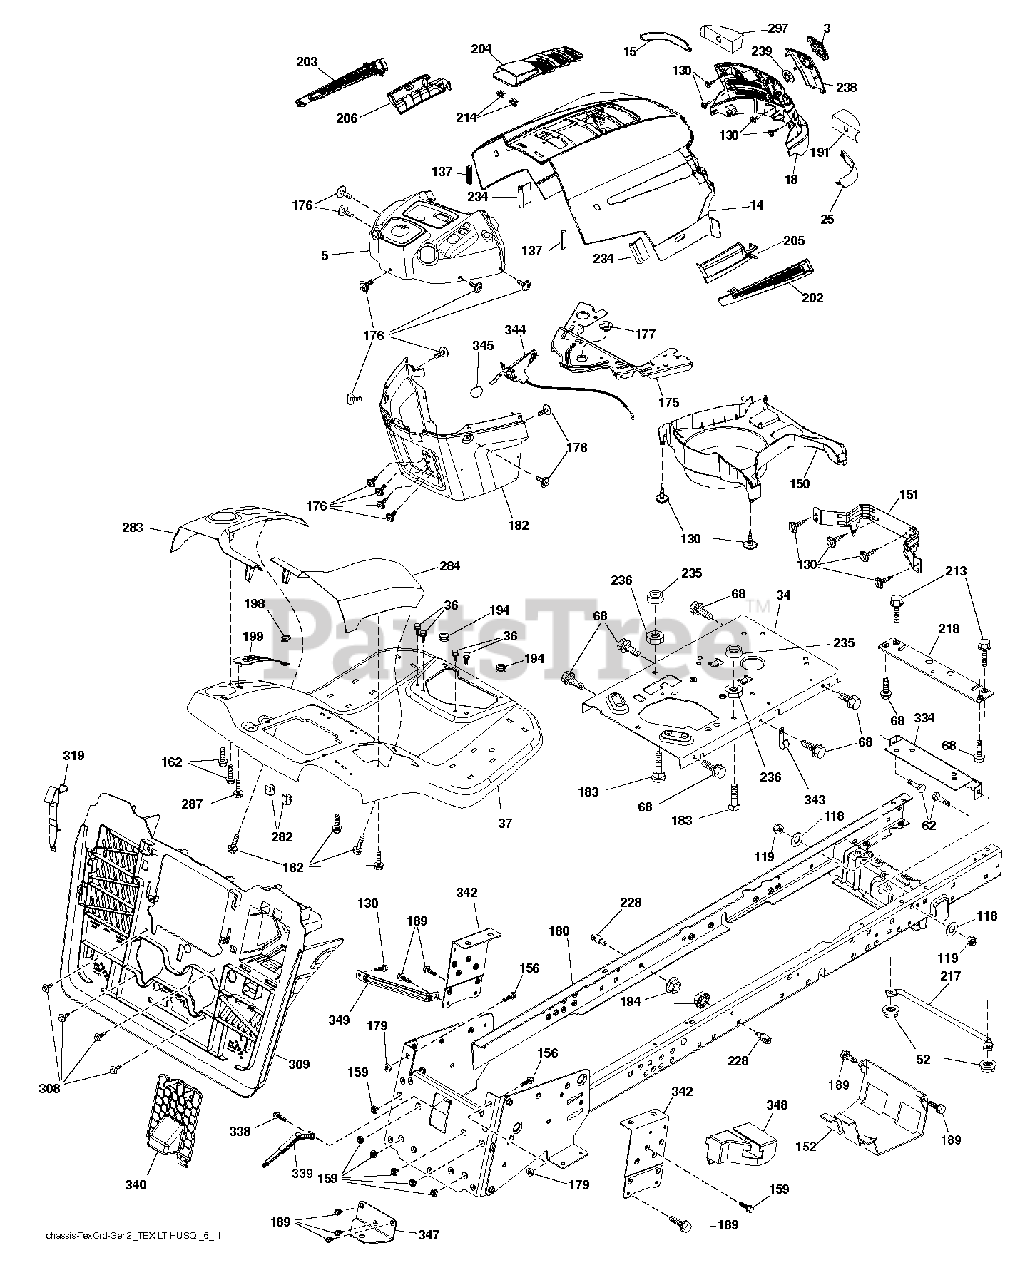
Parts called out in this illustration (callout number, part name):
3	LOGO.HUSQ.GT.LT.CROWN.H
5	SUBASM.DASH.UPPER.HLT.498
14	HOOD.HUSQVARNA.LT.ORANGE
15	LENS.HUSQVARNA LT.RH
18	GRILLE.SVC.HUSQVARNA.GREY
25	LENS.HUSQVARNA LT.RH
36	SCREW 5/16"
37	FENDER.TEX.SRD.CRD.FRN.GUARDS
52	LOCKNUT
62	BOLT D
68	SCREW LT
118	WASHER
130	SCREW.#10 X 0.750.BOS
137	BUMPER DASH
151	BRACKET PIVOT
152	SHIELD.BROWNING.W/TEX
159	SCREW, 3/8-16X3/4
162	SCREW.HI-LO.CONSOLE
175	CROSSMEMBER
176	SCREW.#10-24X5/8.RN.QU
177	BUSHING STEERING
182	DASH DASH. LOWER. PREDATOR. LT
183	BOLT.5/16-18X1-1/4 FULL THD
189	SCREW
191	INSERT.REFLECTIVE.RH.
194	NUT LOCK HEX FLANGE 5/16-18
198	INDICATOR.DECK.LIFT.RED
199	PLATE DECK LIFT
202	VENT.SIDE.HUSQVARNA.LT.RT
203	VENT.SIDE.HUSQVARNA.LT.LFT
204	SUBASM.TOP.VENT.HUSQ.LT
205	SKIRT.SIDE.HUSQVARNA.LT.RT
206	SKIRT.SIDE.HUSQVARNA.LT.LEFT
213	BOLT
214	CLIP.RETAINER.TINNER.
217	ROD.PIVOT.HOOD
218	X-PIECE.HOOD.STOP.NON/
228	STUD.FASTNER.W/ANTI-ROTATE
234	BUMPER.HOOD.TEX.HUSQVARNA
235	SPACER FENDER
236	NUT.CENTERLOCK.5/16-
238	TRIM.HUSQ LT.668
282	CLIP.RETAINER.CONSOLE.LT.HUSQ
283	CONSOLE.DECKLIFT.CRDII.498
284	CONSOLE.PEDAL.HYDRO
287	SCREW 1/4X20
297	INSERT REFLECTIVE
308	BOLT, 5/16-18 X 1 3/4
334	BRACKET.ENGINE
338	BOLT BOLT SHOULDER
339	LEVER LEVER BAGGER
342	SUPPORT SUPPORT FENDER
343	CLIP CLIP
344	CONTROL.EZ.MULCH.TEX/CRD
345	RP KNOB.OVAL.TAPERED.3/8-16BLK
347	HITCH TOW
349	BRACKET.SUPPORT.LRVB/CRD
